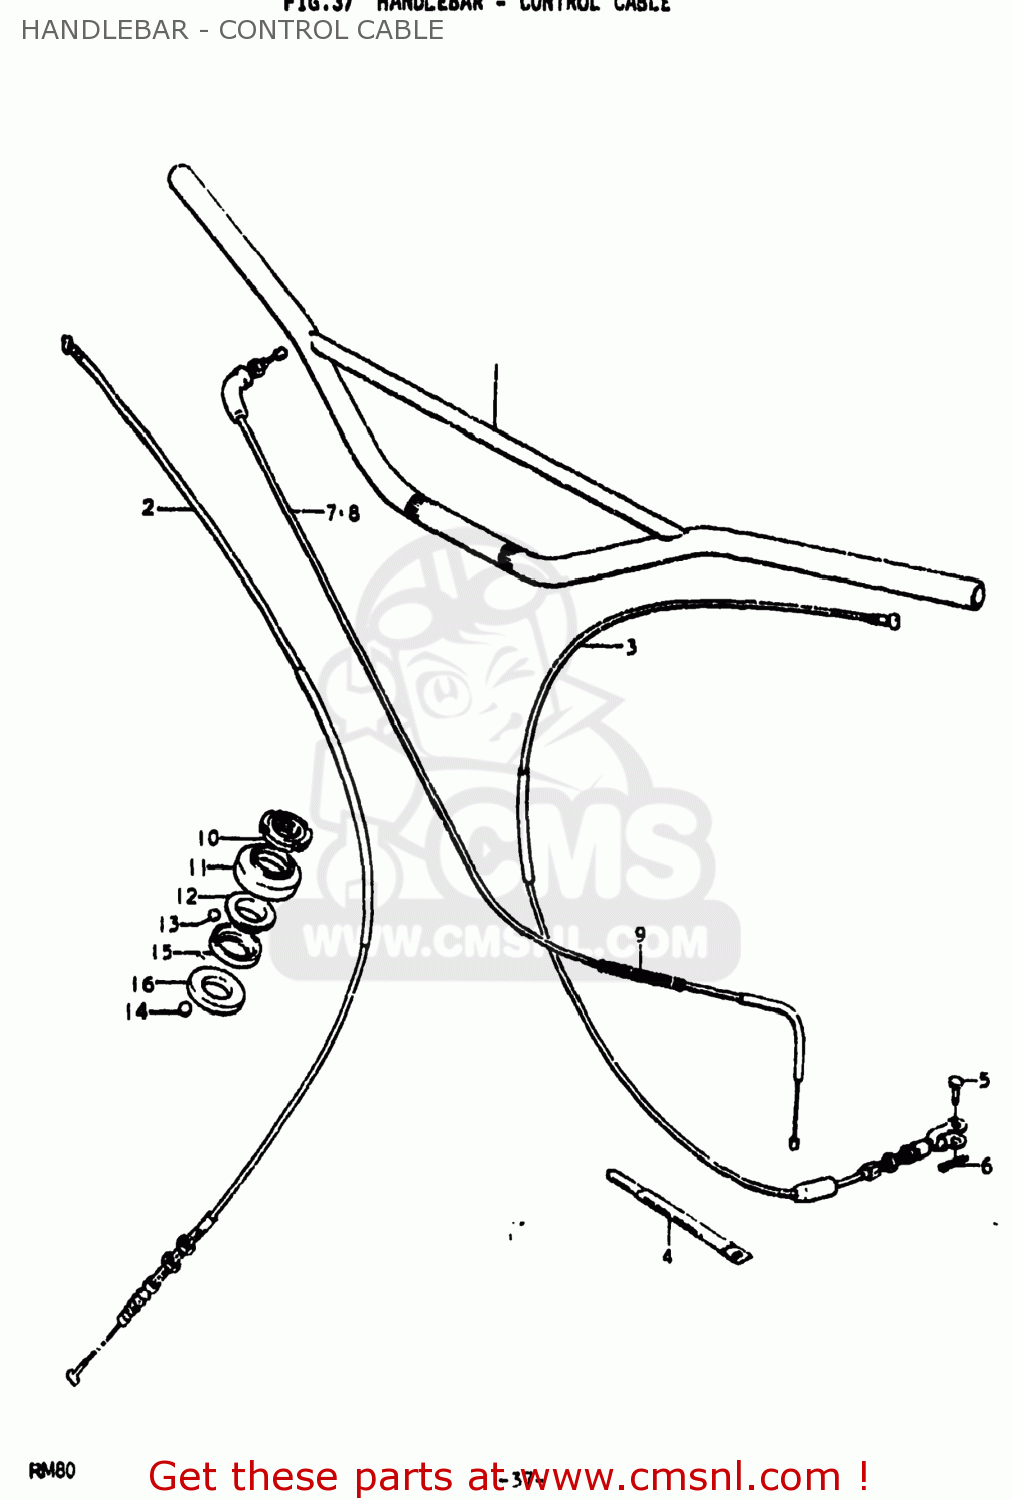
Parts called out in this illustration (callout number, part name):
1	HANDLEBAR
2	CABLE,FRONT BRAKE
3	CABLE ASSEMBLY,CLUTCH
4	CLAMP
5	PIN(L:13)
6	PIN
7	CABLE ASSEMBLY,THROTTLE
8	CABLE ASSEMBLY,THROTTLE
9	PROTECTOR,CABLE
10	NUT,STEERING STEM(25X44X10)
11	DUST SEAL,STEERING UPR
12	RACE,STEERING OUTER UPR
13	BALL
14	BALL
15	RACE,STEERING INNER UPR
16	LACE,STEERING INNER LWR
